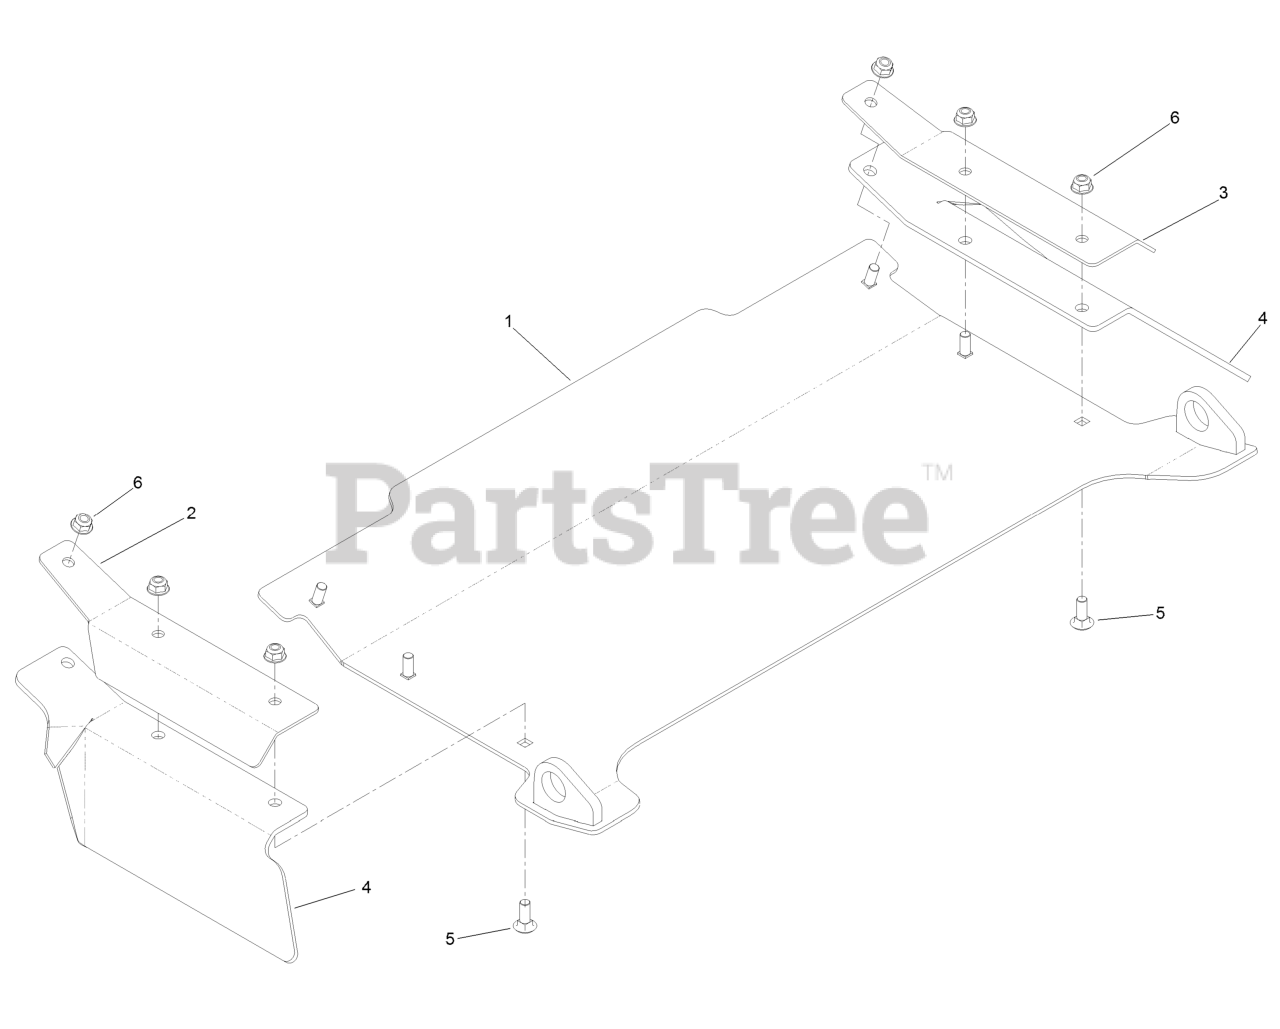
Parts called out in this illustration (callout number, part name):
1	Discharge Tunnel ASM
2	Bracket-Flap, LH
3	Bracket-Flap, RH
4	Flap-Rubber
5	Screw-CARR
6	Nut-HF, NI
